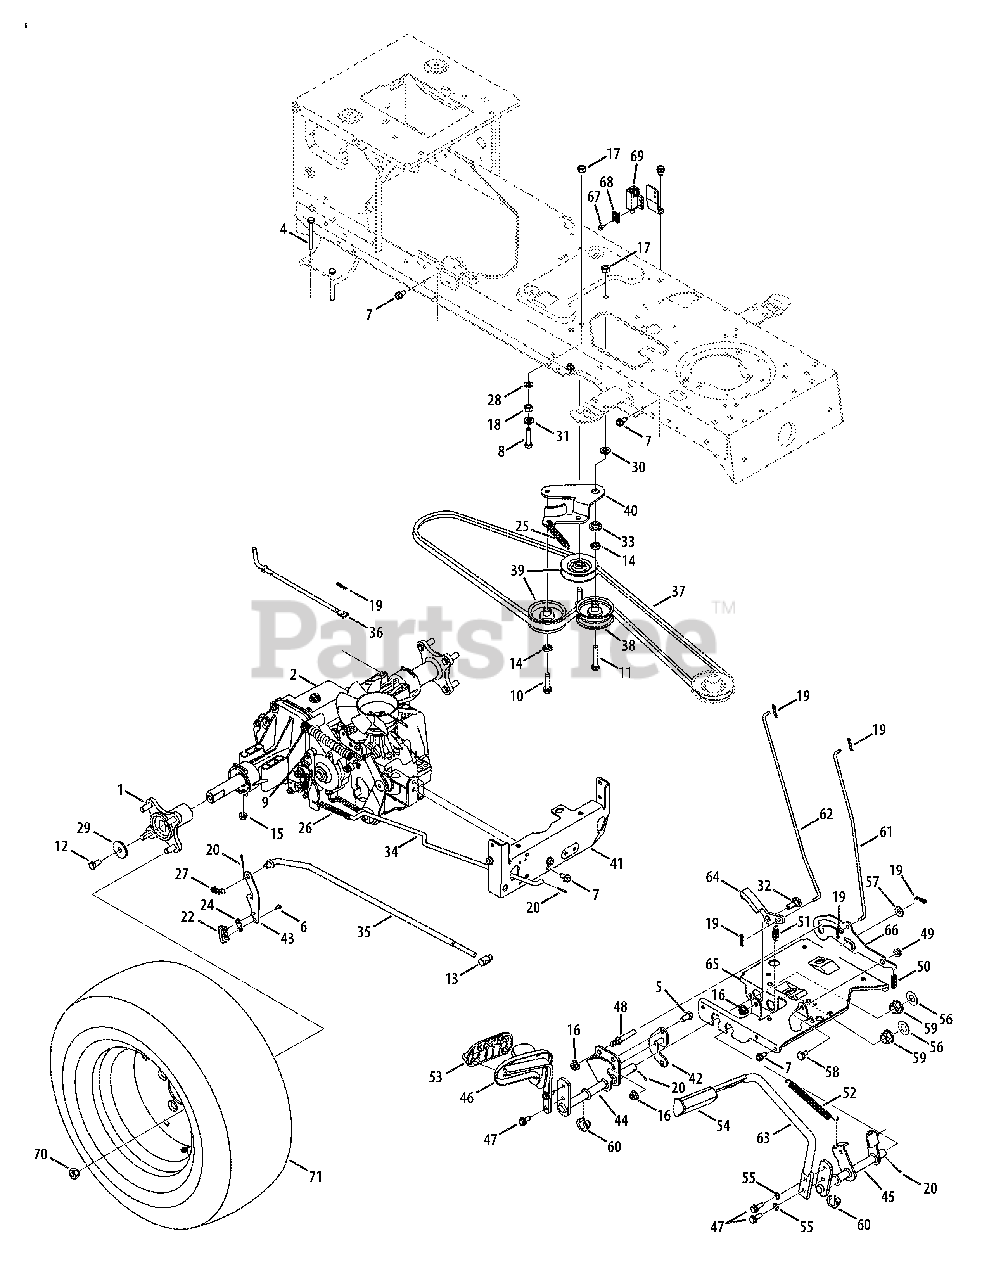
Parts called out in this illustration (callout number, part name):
1	Wheel Hub Assembly
2	Hydrostatic Transmission Assmbly
3	Revse./Grnd. Wire Harness Adptr.
4	Hex Cap Screw, 5/16-18 x 2.75
5	Hex Cap Screw, 3/8-16 x.75
6	Screw, #8-18 x.5
7	Self-tapping Screw, 5/16-18 x.750
8	Hex Cap Screw, 3/8-16 x 1.5
9	Self-tapping Screw, 1/4-20 x.50
10	Hex Cap Screw, 3/8-16 x 1.5
11	Hex Cap Screw, 3/8-16 x 2.25
12	Screw, 3/8-16 x.750
13	Ferrule, 3/8-24
14	Jam Nut, 7/16-20
15	Flange Lock Nut, 5/16-18
16	Flange Lock Nut 3/8-16
17	Hex Nut, 3/8-16
18	Hex Nut, 3/8-16
19	Internal Cotter Pin
20	Cotter Pin
22	Short Spring Switch
24	Insulator Nut Plate
25	Extension Spring,.770 x 3.72 Lg.
26	Extension Spring,.59 x 4.0
27	Extension Spring, 3/8 x 1.44
28	Lock Washer, 3/8
29	Flat Washer,.390 x 1.500 x.134
30	Flat Washer.385 x 1.00 x.135
31	Flat Washer .406 x .875 x .059
32	Shoulder Bolt, .500 x .270
33	Shoulder Spacer,.38
34	Hydrostatic Brake Rod
35	Hydrostatic Control Rod
36	Hydrostatic Bypass Rod
37	Drive Belt
38	Flat Idler Pulley, 2.75
39	V-idler Pulley, 3.06
47	Self-tapping Screw, 5/16-18 x.75
48	Pin, 3/8-16 x 2.43
49	Flange Lock Nut, 5/16-18
50	Compression Spring,.40 OD x 1.17
51	Extension Spring,.50 OD x 1.41
52	Extension Spring,.50 OD x 6.37
53	Drive Pedal Pad
54	Brake Pedal Pad
55	Lock Washer, 5/16
56	Flat Washer,.64 x 1.24 x.06
57	Flat Washer,.385 x.870 x.092
58	Shoulder Screw,.437 x 1.62
59	Hex Flange Bearing
60	Split Hex Flange Bearing
61	Brake Lock Control Rod
62	Cruise Control Rod
64	Cruise Latch
66	Drive Lockout Bracket
67	AB Screw, #10-16 x.500
68	Switch Plate
69	Switch
70	Lug Nut, 3/4-16
